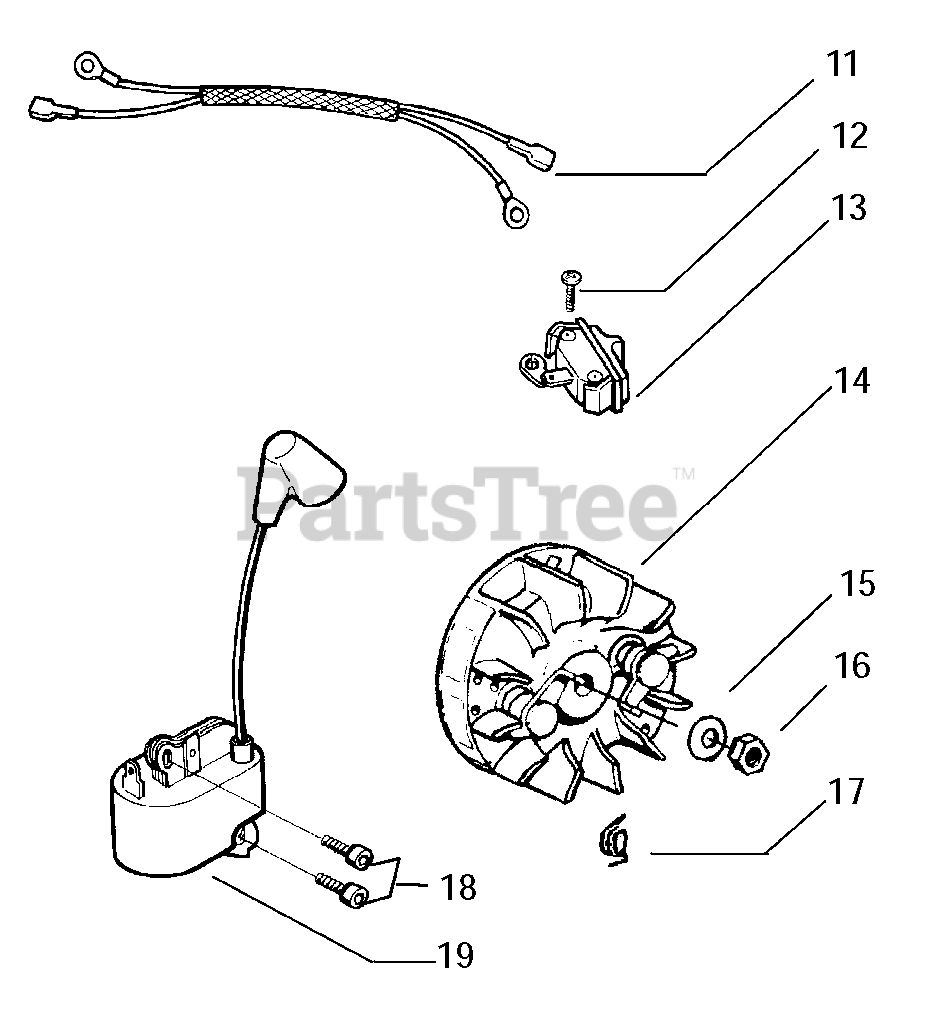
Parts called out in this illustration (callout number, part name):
11	LEAD WIRE ASSY
13	SWITCH ON/OFF
14	ROTOR COMPL. 36/41
15	WASHER-FLYWHEEL
16	NUT-FLYWHEEL
17	SPRING STR DOG
18	SCREW,IGN MOD 36/41
19	%IGNITION MODULE
